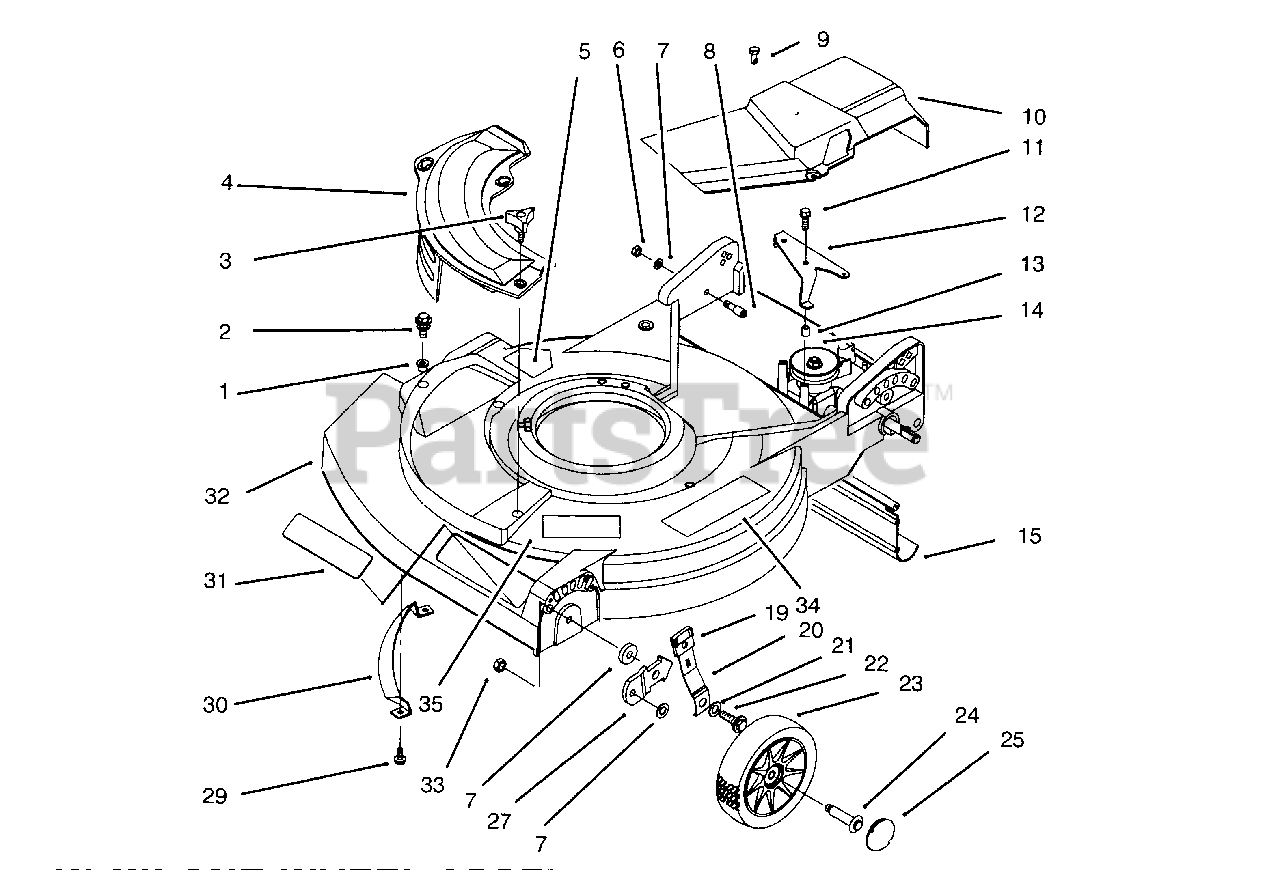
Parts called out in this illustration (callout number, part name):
1	Grommet
2	Screw-Thread Forming
3	Knob
4	Cover-Plate, Mulch
5	Decal-Danger (English)
7	Washer-Wheel Bolt
8	Bolt-Shoulder
10	Cover-Drive
11	Screw
12	Bracket-Actuator
14	Gear Case Assembly
15	Shield-Trailing
19	Knob-Spring Arm
20	Spring Arm Assembly
21	Washer-Belleville
22	Bolt-Shoulder
23	Wheel-6"
24	Bolt-Wheel
27	Bracket-H. O. C.
30	Bar-Toe
31	Applique
32	Housing-21 (Incl. Ref. #5 & 31)
33	Nut-Lock
34	Decal-Warning
35	Decal-No Rust
